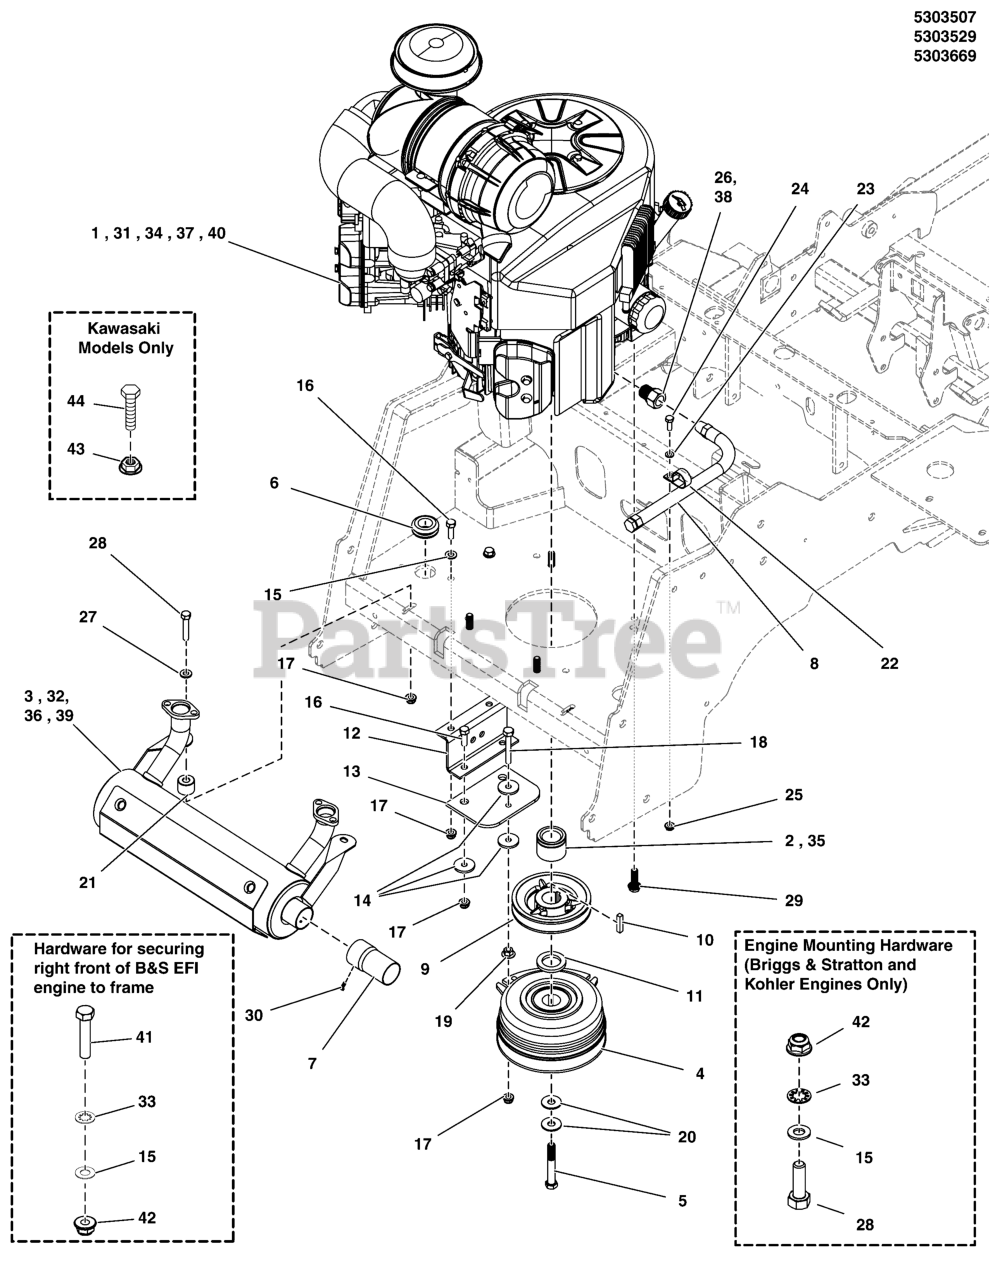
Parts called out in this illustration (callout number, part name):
2	SPACER, 1.13 X 1.75 X 1.35, CZ
3	MUFFLER, 27HP KAWASAKI, 5" CAN
4	CLUTCH,5218-221, WARNER
5	BOLT, CRANKSHAFT, 7/16-20 X 3, GD8
6	GROMMET, 7/8"ID, 1/4" THICK STK
7	EXTENSION, TAILPIPE, 3" - BLACK
8	HOSE, OIL DRAIN
9	PULLEY, 4.75 OD X 1-1/8 BORE, BC-48
10	KEY, 1/4 SQ X 1-1/4
11	SPACER, 1.13 X 1.75 X .25
12	ANCHOR, CLUTCH, IS600-IS700 - BLK
13	CLUTCH ANCHOR PAD
14	WASHER, .34 X 1.25 X 10 GA
15	WASHER, 5/16" SAE
16	BOLT, 5/16-18 X 1 GD5 YZ
17	NUT, 5/16-18 HEX NYLOCK FLANGE
18	BOLT, 5/16-18 X 2-1/4 TFL, GD5 YZ
19	NUT, 5/16-18 HEX SERRATED FLANGE (LARGE)
20	BELLEVILLE WASHER 1.1875 X .442 X .089
21	SPACER, .39 X 1.00 X .80, CZ
22	CLAMP, VINYL INSULATED
23	WASHER, 1/4 SAE
24	BOLT, 1/4-20 X 3/4 GD5 YZ
25	NUT, 1/4-20 HEX SERR. FLANGE
26	ADAPTER-OIL DRAIN
27	WASHER, 5/16 F436 FLAT
28	BOLT, 5/16-24 X 1-3/4, GD8
29	BOLT, 3/8-16 X 1-1/4, SF, PLT W/PATCH
30	SCREW,SELF-TAP,#8-32 X 3/8,WASH HEX, CZ
31	ENGINE, B&S, VANGUARD
32	MUFFLER, RIGHT OUTLET ASSY
33	WASHER, 5/16 INT. TOOTH LOCK
35	SPACER, 1.13 X 1.75 X 1.35, CZ
36	MUFFLER (see Engine Service Parts)
38	METRIC ADAPTER, M14-1.5" TO 3/8 NPTF
39	MUFFLER, ASSY, SERVICE PART
41	BOLT, 5/16-24 X 1-1/2, GD8, PHOS
42	NUT, 5/16-24, TOP LOCK FLANGE, GD8 PHOS
43	NUT, M8-1.25 SERR. FLANGE, CZ
44	BOLT, M8-1.25 X 16MM GD8.8
